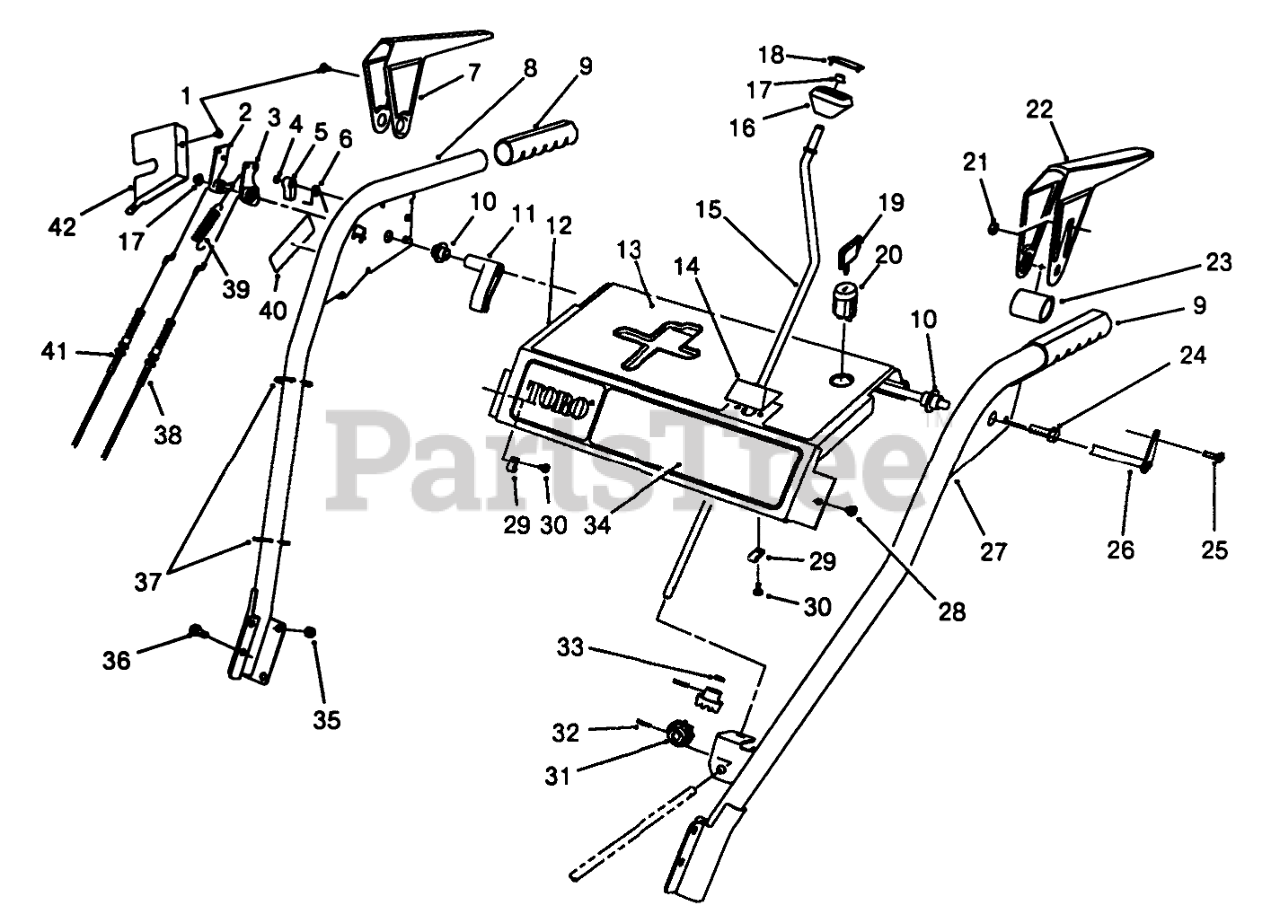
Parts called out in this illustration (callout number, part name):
1	SCREW-HH
2	TANG-LOCKING
3	CAM-RELEASE
4	E-RING-RETAINER
5	LATCH-LOCKING
6	SPRING-TORSION
7	Lever-Impeller
8	Handle-RH
9	HANDLE GRIP
10	BUSHING-LEVER
11	LEVER-TRIP
12	Panel-Control
13	Decal-Panel, Top
14	PLATE-GUIDE
15	CRANK-ROD, CHUTE
16	KNOB-CONTROL, CHUTE
17	RETAINER-PUSH ON
18	COVER-KNOB
19	KEY-IGNITION
20	SWITCH
21	NUT-LOCK, NI
22	Lever-Traction
23	SPACER-LEVER, TRACTION
24	SCREW-HHF
25	SCREW-HWH
26	CROSS ROD ASM
27	LH HANDLE WA (24")B
28	SCREW-HWHTF
29	R CLAMP
30	SCREW-PPH
31	GEAR-UNIVERSAL
32	PIN-SPRING
33	WASHER-RUBBER
34	DECAL-FRONT PANEL (824)
35	NUT-LOCK, NI
36	SCREW-HHF
37	TIE-CABLE
38	CABLE-TRACTION
39	Spring-Extension
40	Decal-Warning
41	CABLE-IMPELLER
42	Cover Lever Lock
